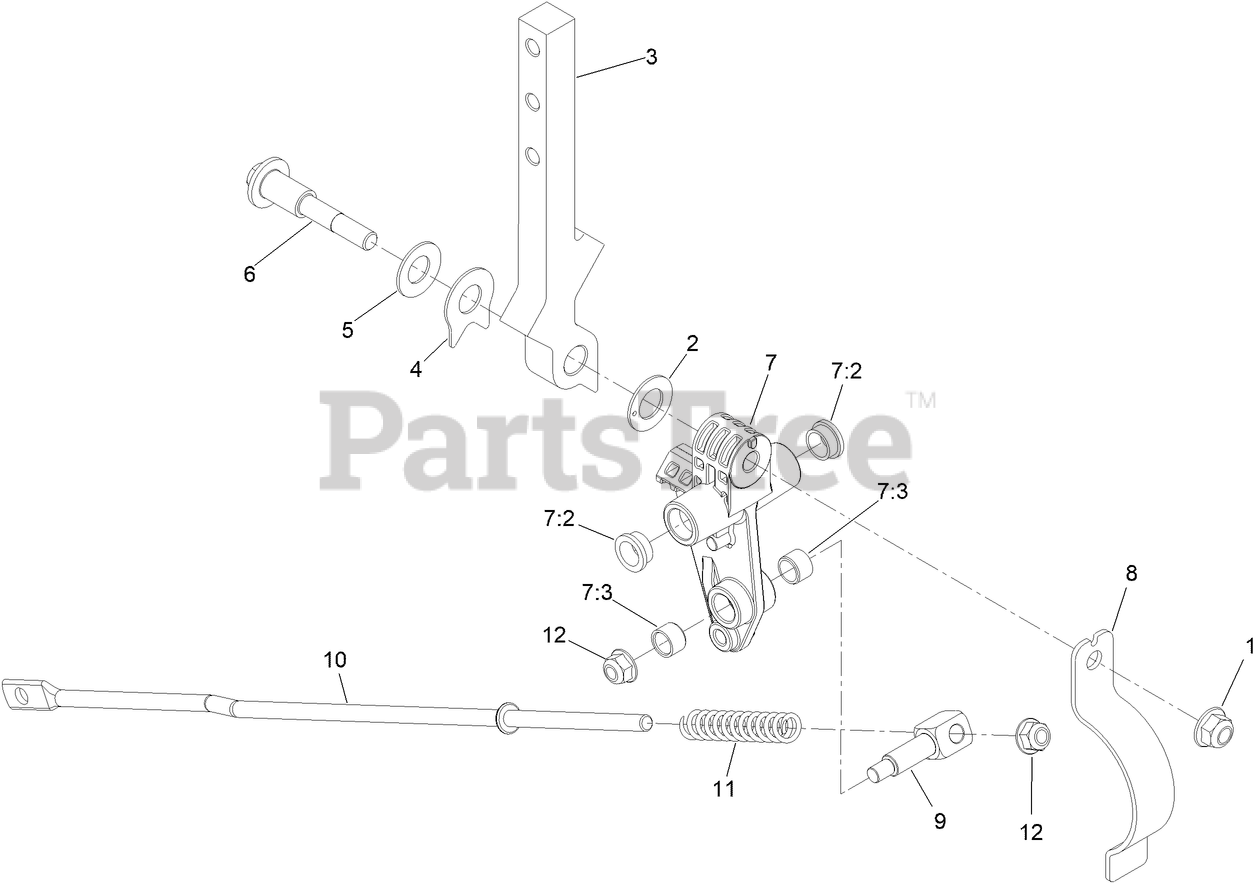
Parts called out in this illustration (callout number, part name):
1	NUT-HF, NI
2	WASHER-FRICTION
3	ARM-CONTROL
4	SPACER, ANTI-ROTATION
5	WASHER-BELLEVILLE
6	BOLT-PIVOT
7	ASM-CONTROL ARM
7:2	BUSHING
7:3	BUSHING-SLEEVE
8	SPRING-RTN
9	SWIVEL
10	LINK-CONTROL
11	SPRING-RETURN, NEUTRAL
12	NUT-HF, NI
